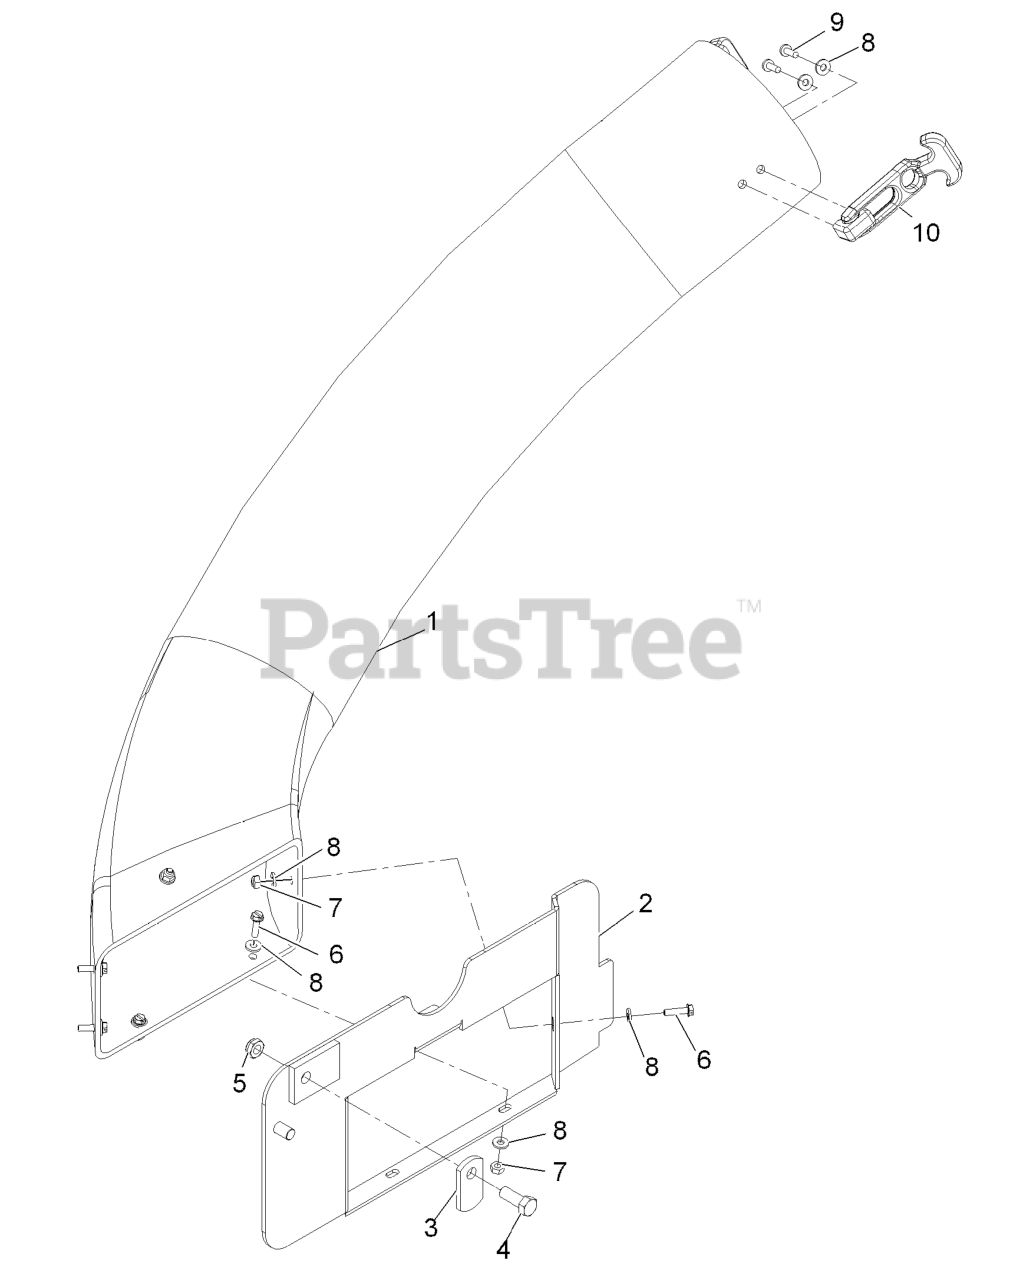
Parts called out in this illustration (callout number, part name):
1	BOOT-LOWER
2	BOOT FRAME ASM
3	LATCH-CATCHER, GRASS
4	SCREW-HH
6	SCREW-HWH
7	NUT-LOCK, NI
8	WASHER-FLAT
9	SCREW-PPH
10	LATCH-RUBBER
